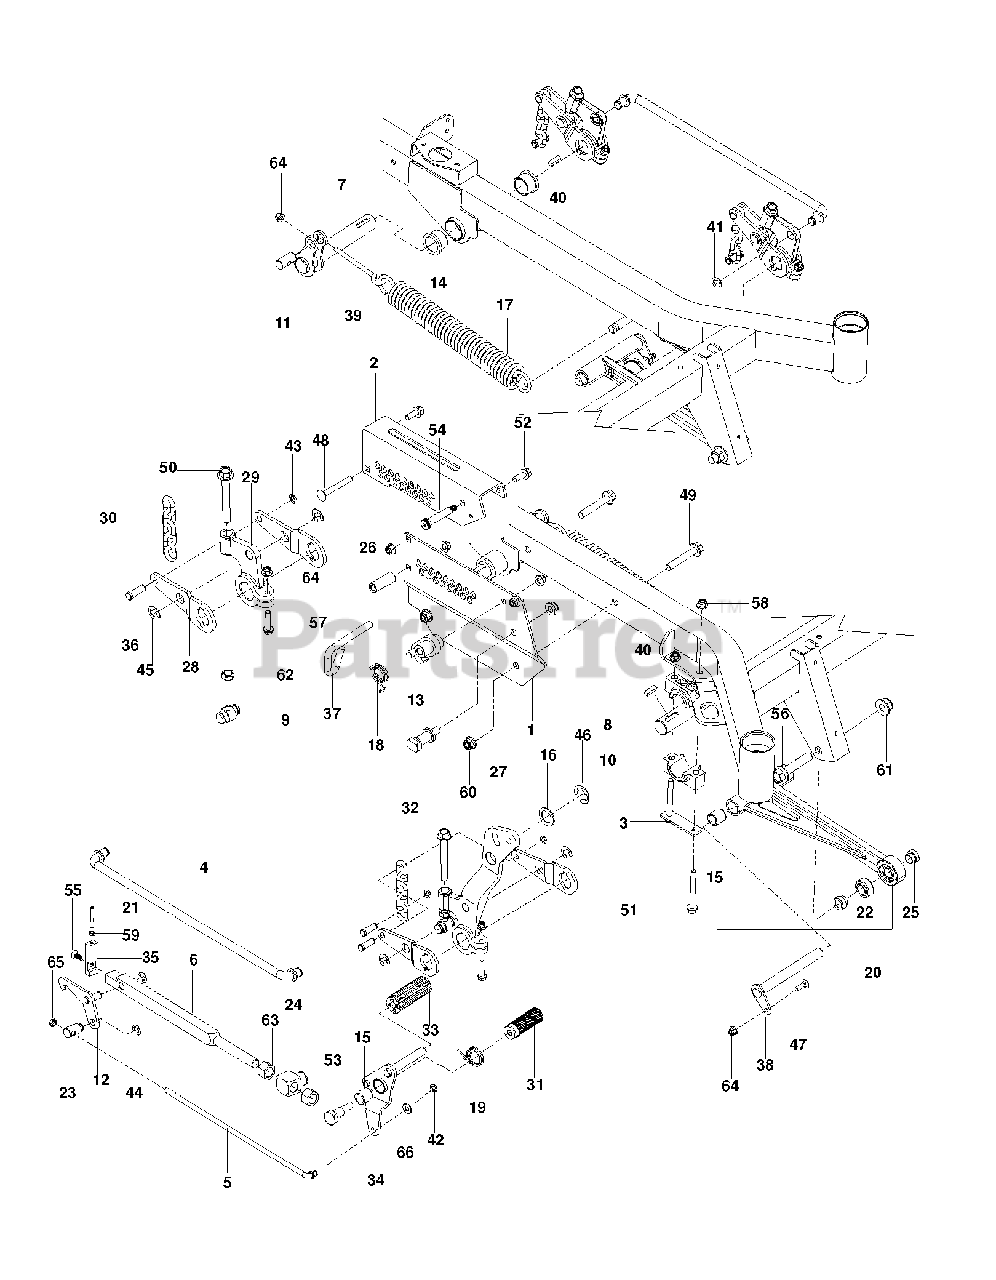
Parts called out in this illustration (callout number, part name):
1	PLATE, INNER HEIGHT, BLUE
3	PLATE, PILLOW BLACK
4	ROD, LIFT
5	ROD, HEIGHT LATCH
6	BAR, HEIGHT
7	SHAFT, RR LIFT
8	SHAFT, LIFT, FT
9	SHAFT, LIFT TRUNION
10	BLOCK, PILLOW
11	PIVOT, SPRING
12	LATCH, HEIGHT WLDMT
13	LATCH, TRANSPORT WLDMT
14	BUSHING, FLANGE 1.25 X 1.0
15	BUSHING, SLEEVE 3/4 X 1.0
16	MACHINE BUSHING
17	SPRING, EXTENSION
18	SPRING, TORSION
19	SPRING, TORSION
20	ASSEMBLY, STRUT
21	LINK, INDICATOR
22	BALL JOINT, 3/4" SWIVEL
23	SWIVEL, HEIGHT LATCH
24	SWIVEL, HEIGHT BAR
25	SPACER, STRUT
26	SPACER, HEIGHT PLATE
30	LIFT CHAIN
31	PAD, FOOT PEDAL
32	GUIDE, HEIGHT BAR
33	PEDAL, DECK HEIGHT
34	PEDAL, RELEASE WLDMT
35	CAP, HEIGHT BAR
36	PIN, 7/16 CLEVIS
37	PIN, HEIGHT
38	PIN, STRUT
39	EYE BOLT 4.5`
40	KEY, 5/16 SQ X 1.0
41	5/8 E-RING
42	E RING 3/8"
43	RING, E, 7/16
44	E-RING 1/2
45	E RING 3/4
46	E-RING 1"
47	RHSNB 5/16C X 1
48	3/8-16 X 3` CARR BOLT
49	HFFS 1/2-13 X 3 GD 5 ZD
50	HHFS 1/2-13 X 4 GR 5
51	HHFS 3/8-16 X 3.5 GD 5 ZD
52	HHFS 3/8-16 X 1 GRD 5 ZD
53	BOLT, SHOULDER
54	BOLT, SHOULDER, 1/2 X 2.25
55	SCREW, 5/16-18 X 3/4 FLAT HEX
56	HHFS 5/8-11 X 3.0 GD 8 ZD
57	HHFS 5/16-18 X 1.5 GD 5
58	NUT 3/8-16 HEX FLG NYLOC ZD
59	NUT 1/4-20 JAM
60	NUT, 1/2-13 HEX FLG NYLOC ZD
61	NUT 5/8-11 FLG NYLOC ZD
62	NUT 1/2 HEX JAM
64	5/16-18 NYLOC FLANGE NUT
65	NUT 3/8-24 JAM
66	WASHER 3/8 SAE FLAT
